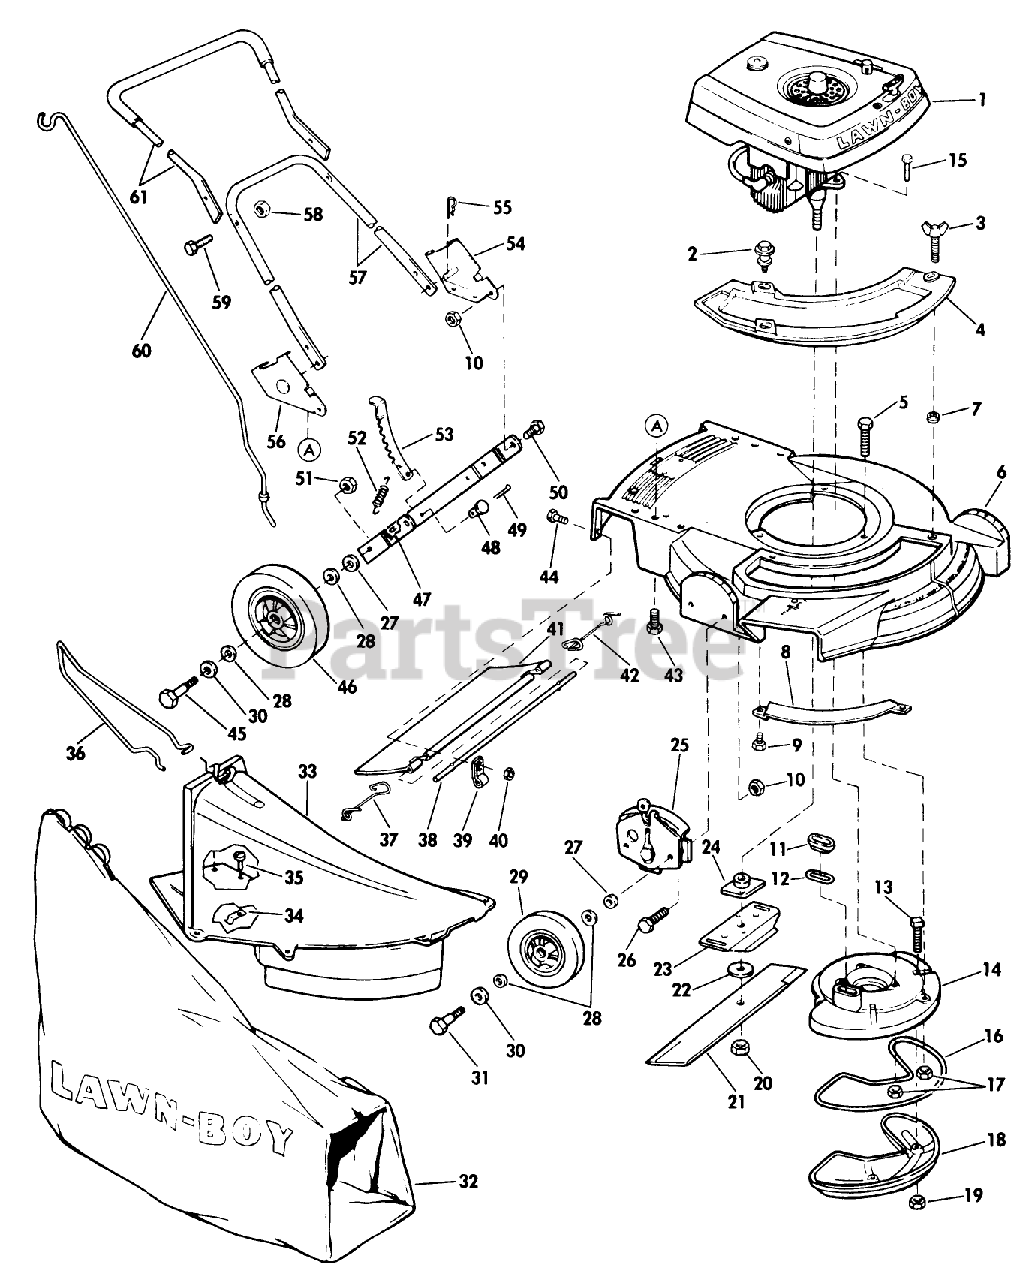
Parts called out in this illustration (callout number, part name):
3	WING SCREW LAWRE
5	SCREW
8	TOE BAR 19"
8	BAR-TOE
10	NUT
11	SLEEVE
12	GASKET S
17	NUT-LOCK F
20	NUT-BLADE
22	WASHER
24	PLATE AND COLLAR ASM
27	WASHER WROUGHT
28	WASHER
30	SPACER
31	BOLT WHEEL
32	ORD LB 89802 WHOLE GOODS
37	SPRING;TRAILING SHIELD RH
38	ROD T/SHIELD ADV WIRE
38	ROD 21" ADVANCE
39	CLAMP ROD KMC
42	SPRIG T/SHLD ASOC
43	SCREW
45	BOLT
50	BOLT-SHOULDER
51	LOCKNUT
52	SPRING N.A.S
55	HAIR PIN
59	SCREW
60	ROD GRASSBAG
